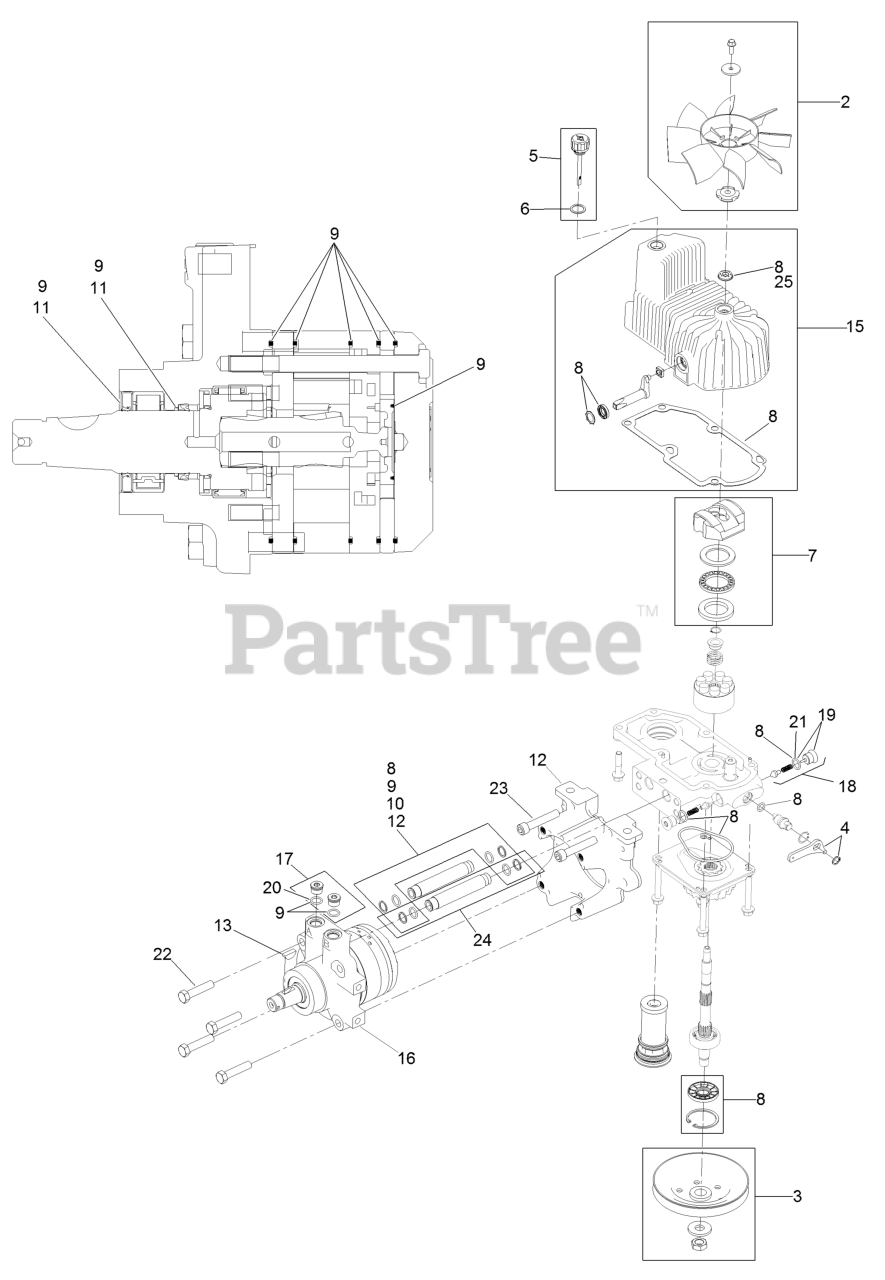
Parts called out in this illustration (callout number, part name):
2	FAN KIT
3	PULLEY KIT
4	HANDLE-BYPASS VALVE, HYDRO
5	DIPSTICK-HYDRO W/GASKET
6	GASKET-DIPSTICK, HYDRO
7	SWASH BLOCK KIT
8	PUMP SEAL KIT
9	MOTOR SEAL KIT
10	TUBE SEAL KIT
11	OUTPUT SHAFT SEAL KIT
12	NOSE CUP-UHT
13	KEY-WOODRUFF
15	HOUSING-HYDRO, LH
16	MOTOR-HYDRAULIC LH 240CC
17	MAGNETIC PLUGS SERVICE KIT
18	CHECK VALVE ASM
19	PLUG-CHECK (W/O-RING)
21	O-RING-CHECK VALVE
22	SCREW HH
23	SCREW-HSH
24	HYDRAULIC TUBE KIT
25	SEAL-FAN DRIVE
